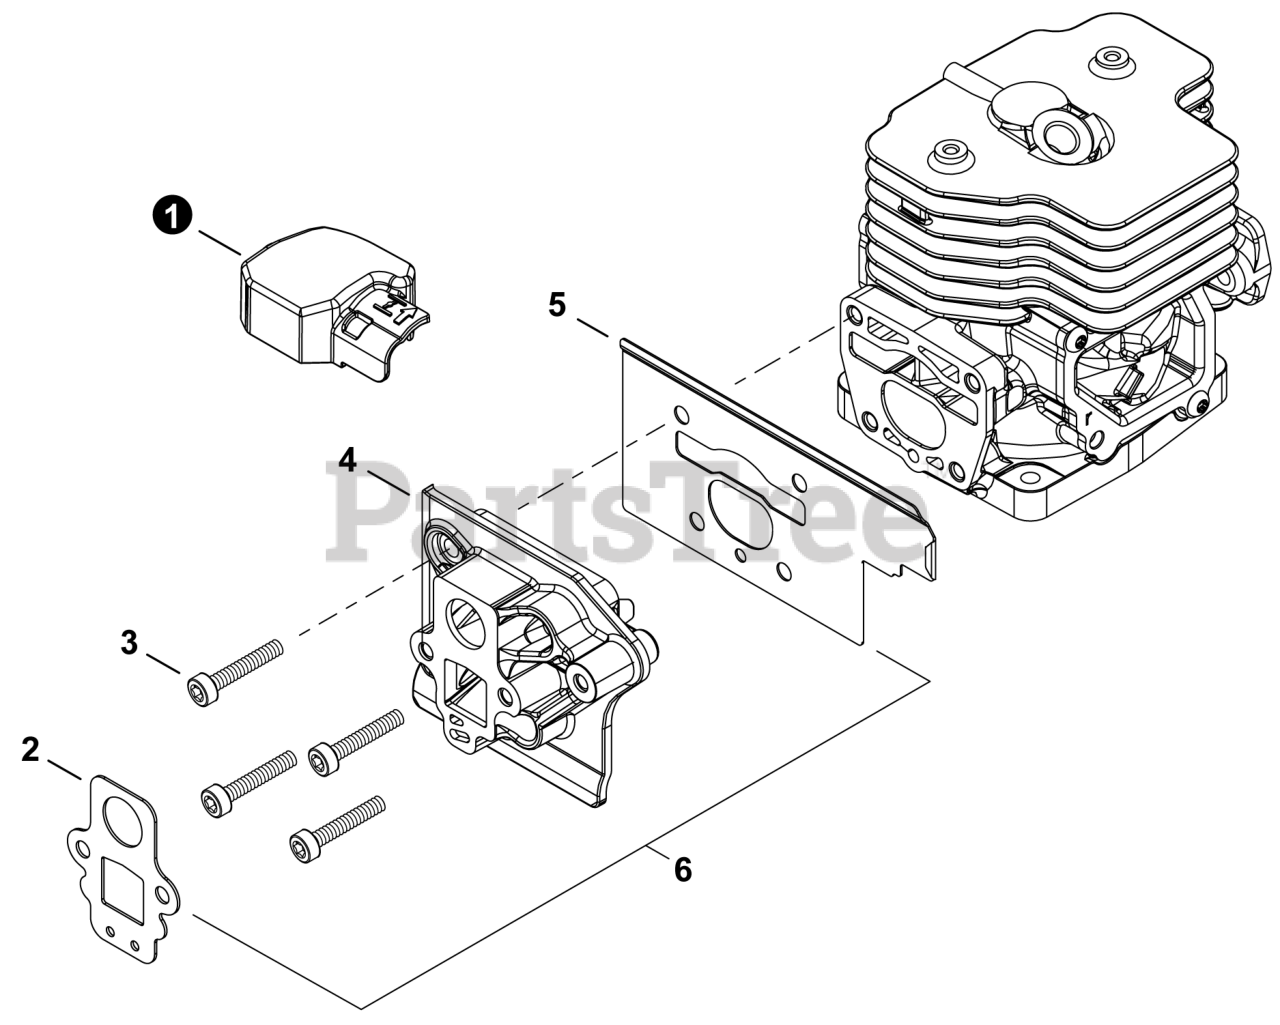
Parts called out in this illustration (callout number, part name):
1	CAP, CARBURETOR
2	GASKET, INTAKE
3	BOLT 5x25
4	INSULATOR, INTAKE
5	HEAT SHIELD, INTAKE
6	GASKET KIT: ENGINE, INTAKE, EXHAUST
